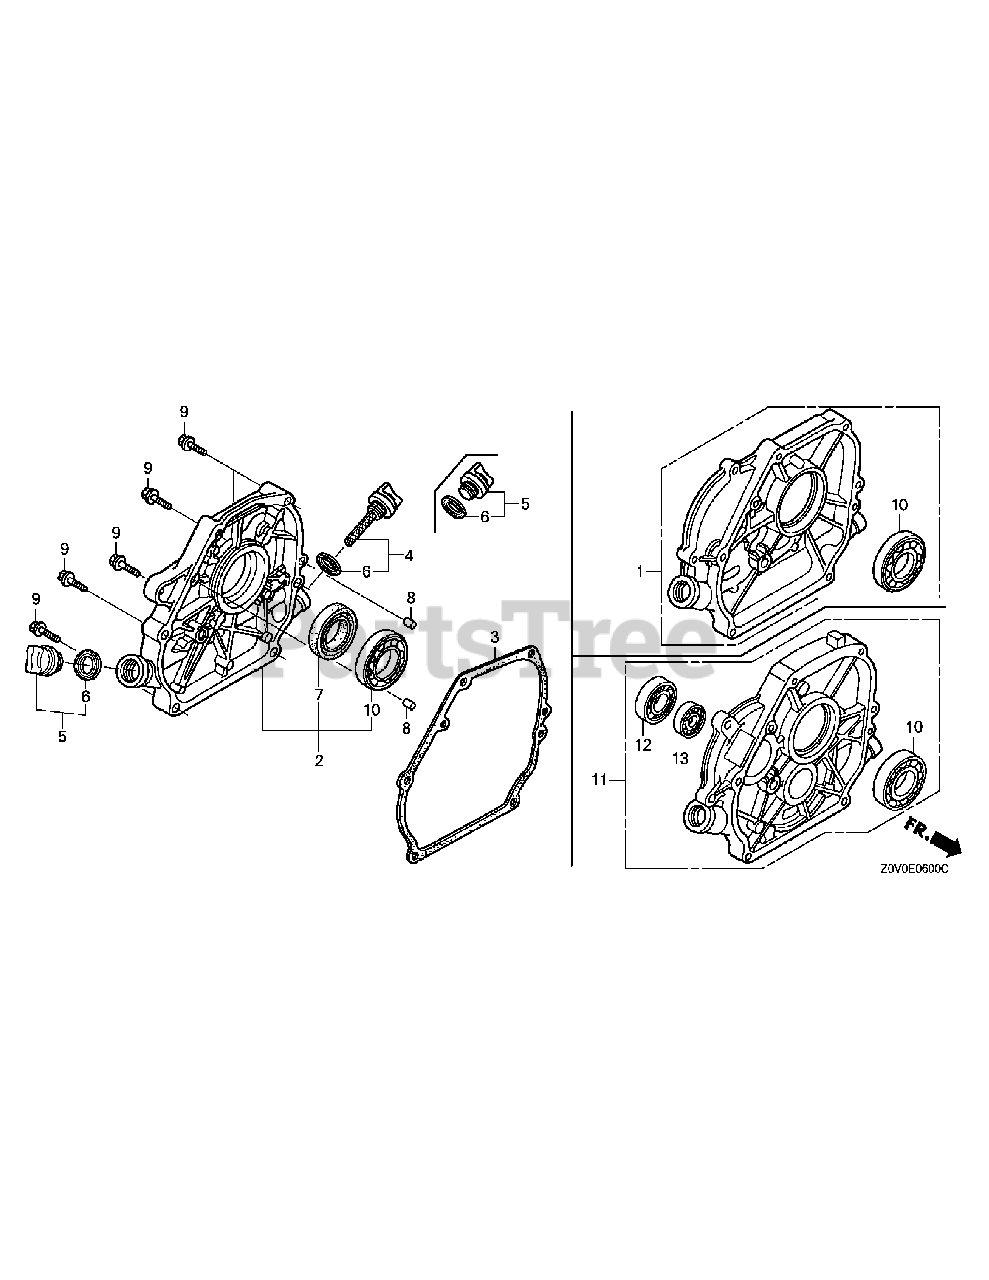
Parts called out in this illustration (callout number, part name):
2	Cover Assy., Crankcase
3	Packing, Case Cover (Non Asbestos)
4	Cap Assy., Oil Filler
5	Cap Assy., Oil Filler
6	Packing, Oil Filler Cap
7	Oil Seal, 25X41X6
8	Dowel Pin, 8X14
9	Bolt, Flange, 8X32
10	Bearing, Radial Ball, 6205
11	Cover Assy., Crankcase
12	Bearing, Radial Ball, 6004
13	Bearing, Radial Ball, 6202
